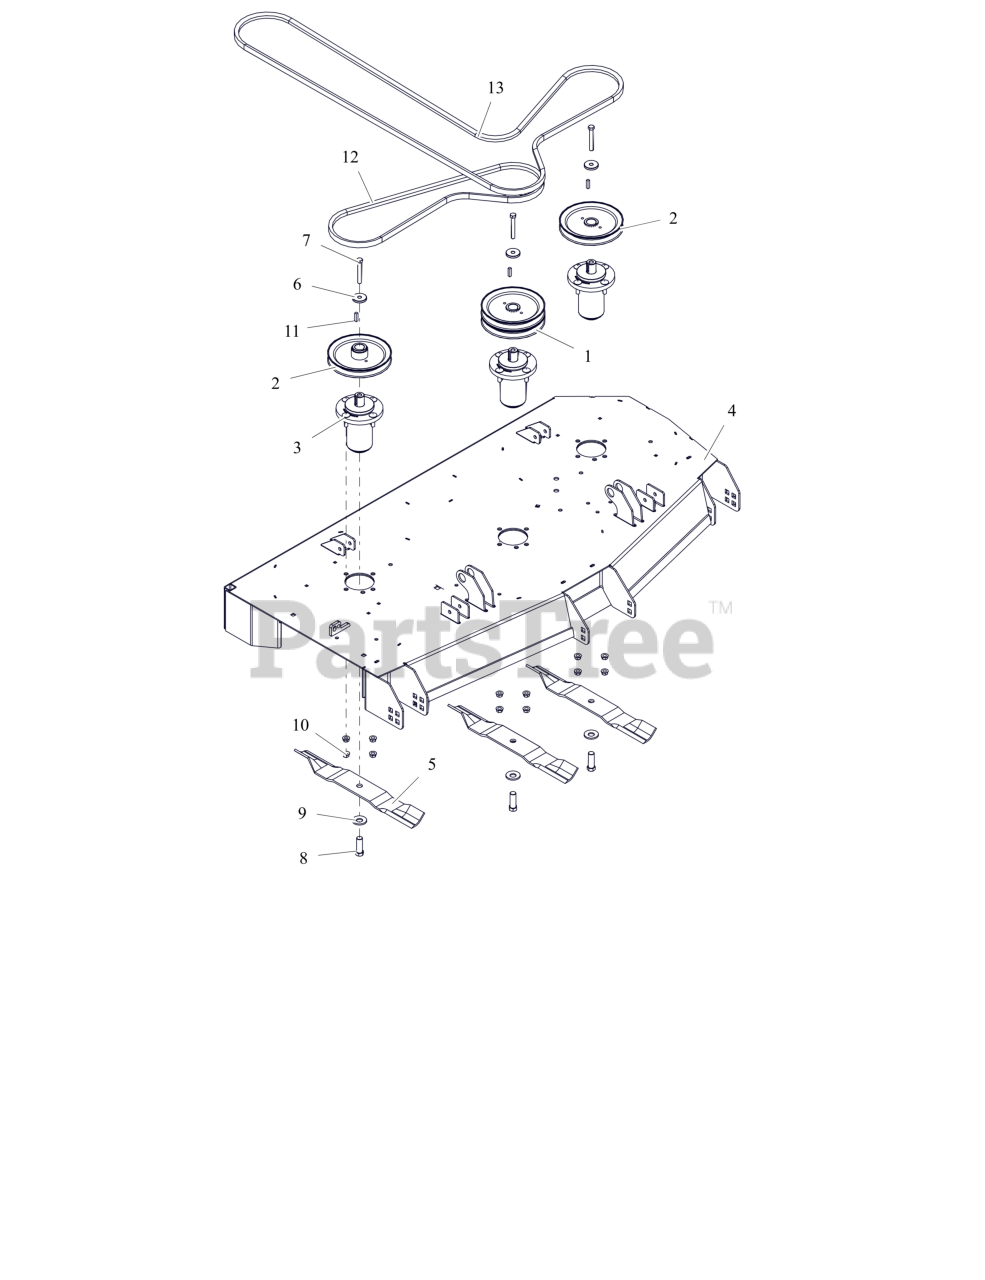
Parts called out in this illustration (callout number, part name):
1	PULLEY, DOUBLE 1.000 ID X 6.750 OD
2	PULLEY, V-1" ID X 6.75 OD
3	ASM, MAINT FREE ALUM SPINDLE
4	KIT, DECK - 52 W/DECALS - XF3
5	BLADE, 18"
6	RETAINER, SHEAVE
7	BLT, HEX .38-16X2.75 G8 ZCC
8	BLT, HEX .62-18X1.75 G8 ZCC
9	WSHR-BLVL .669X1.535X.138
10	NUT-LK-CTR-FLG .375-16 GF ZCC
11	KEY, SQ .25X.25X1.00 RC 40-50
12	V-BELT, B-COGGED
13	V-BELT, HB SECTION
